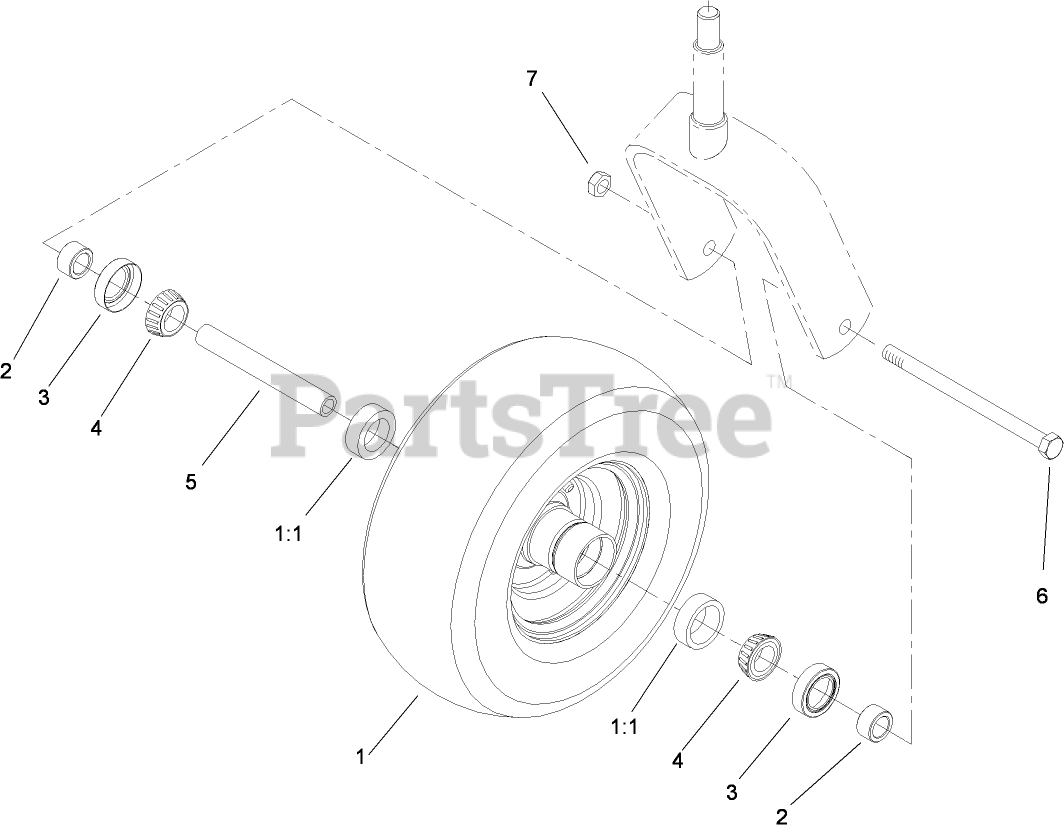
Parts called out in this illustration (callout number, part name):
1	WHEEL AND TIRE ASM (SEMI-PNEUMATIC)
1:1	BEARING-CUP
2	SPACER-BEARING
3	SEAL-BEARING
4	BEARING-CONE, TAPER
5	SPACER-CASTER, FRONT
6	SCREW-HH
7	NUT-LOCK, NI
